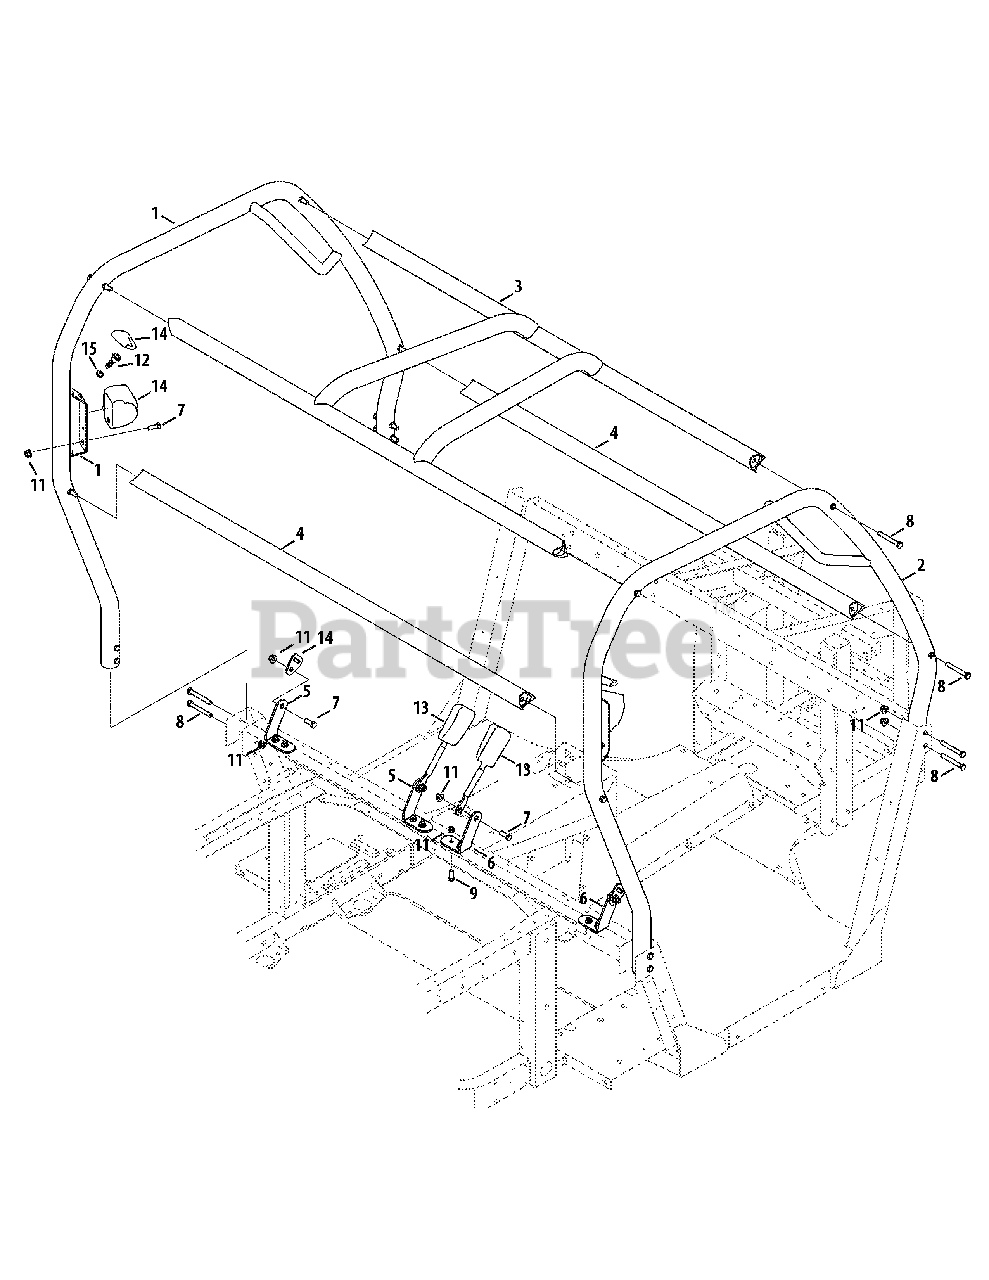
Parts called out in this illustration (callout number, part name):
1	Frame Assembly, OPS, LH
2	Frame Assembly, OPS, RH
3	Frame Assembly, OPS, Roof
4	Frame Assembly, OPS, Frt
5	Bracket, Seat Belt, LH
6	Bracket, Seat Belt, RH
7	Screw, 3/8-16 x 1.00
8	Screw, 3/8-16 x 2.75
9	Screw, 5/16-18 x .875
10	Nut, Flange Lock, 5/16-18
11	Nut, Flange Lock, 3/8-16
12	Shoulder Bolt, 7/16-20
13	Belt, Seat
14	Belt, Seat
15	Nut, Hex Lock, 7/16-20
